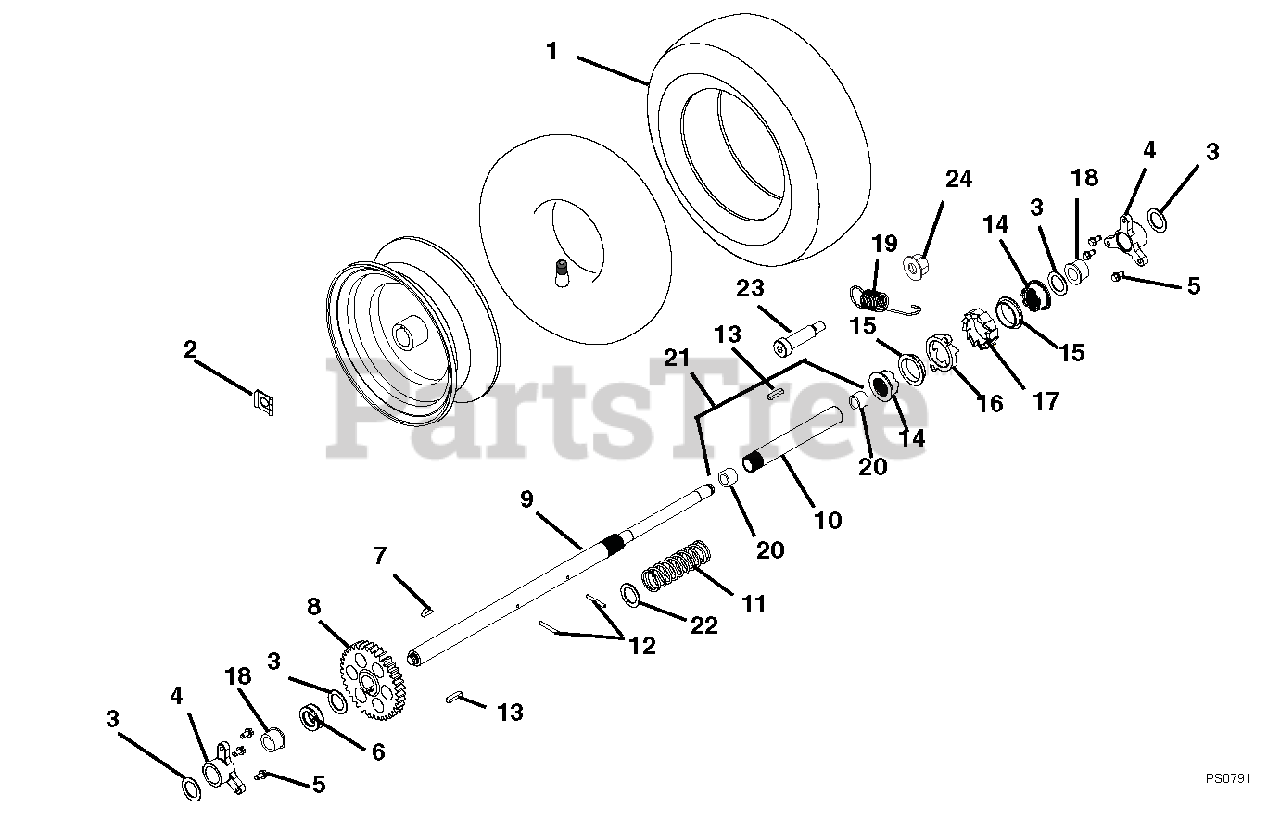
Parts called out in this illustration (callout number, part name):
1	TIRE/WHEEL,RH 15X5.00-6 REMOTE
2	CLIP, SNAP .625 DIA
3	WSHR-FL-STL 1.010X1.505X.062YZ
4	BUSHING, RAKE SHAFT 1"
5	SCR-TAP .25-20X.50 HWH TR YWZ
6	BSHG-SLV, 1.012X1.125X1.00
7	KEY-WDRF .25X.750X.313 SAE91
8	GEAR, SPUR
9	AXLE, LONG - CLICKER
10	AXLE, SHORT - CLICKER
11	SPRING, COMPRESSION
12	PIN-ROLL .188X1.25
13	KEY-RECT .25X.188X1.00
14	CLUTCH, DOG - SLIDING
15	BUSHING, FLANGE
16	GEAR, CLUTCH
17	GEAR, RATCHET
18	BSHG-FLG SPLIT NYLINER 1.0" HP
19	SG-TENS .06X.62X2.94
20	BSHG-SLV .706X.764X.75 BRZ
21	AXLE, CLICKER W/BUSHINGS
22	WSHR-FL-STL 1.010X1.250X.068YZ
23	BLT-SHLDR .50X1.50 .38-16X.625
24	@NUT-LK-TOP-FLG .38-16 YWZC
